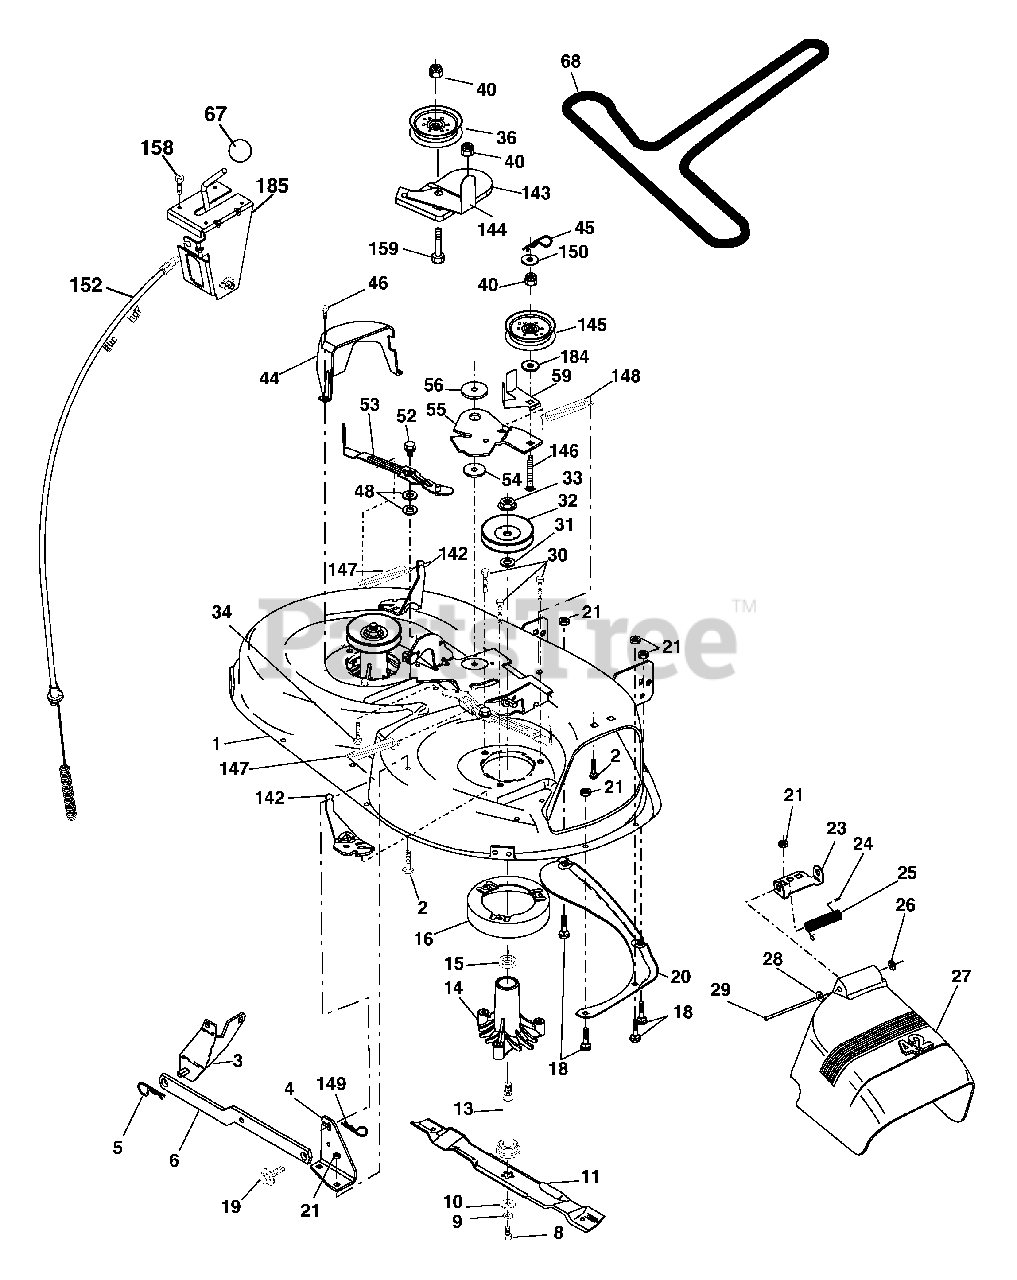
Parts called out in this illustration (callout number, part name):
1	Mower Deck Assembly, 42"
2	Bolt
3	Bracket Asm Fr. Sway Bar 3/42
4	Bracket Asm Deck 42" Sway Bar
5	Retainer Spring
6	Bar Sway Deck
8	Bolt 3/8-24 x 1.25 Gr. 8 patched
9	Washer, Lock
10	Washer, Hardened
11	Blade Mower 42" Hi-Lift
11	Blade, Mulching 42" Std
11	Blade Mulching 42" Premium
13	Shaft Assembly, Mandrel, Vented
14	Housing, Mandrel, Vented
15	Bearing, Ball, Mandrel
16	Stripper, Mandrel Deck
18	Bolt, Carriage 5/16-18 x 5/8
19	Bolt, Shoulder
20	Baffle, Vortex
21	Nut
23	Bracket, Deflector Mower 42"
24	Cap, Sleeve 80 x 112 Blk Mower
25	Spring, Torsion, Deflector 2 52
26	Nut, Push Phos & Oil
27	Shield, Deflector 42" Blk
28	Washer 11/32 x 5/8 x 16 Ga.
29	Rod, Hinge 42" 6 75 W/G
30	Screw Thdrol
31	Washer, Spacer Mower Vented
32	Pulley, Mandrel
33	Nut, Toplock
34	Bolt Carr SH 3/8-16 x 1-1/2 Gr.5
36	Pulley, Idler, Flat
40	Nut Lock 3/8-16
44	Guard, Mandrel, LH
45	Retainer
46	Screw, Thdrol 1/4-20 x 5/8 T
48	Washer, Hardened
52	Bolt, Shoulder 5/16-18 unc
53	Arm Assembly, Pad, Brake
54	Washer, Hardened
55	Arm, Idler
56	Spacer, Retainer
59	Guard TUV Idler
67	Knob Round
68	V-Belt, 42" Mower
142	Arm Spring Brake Mower
143	Bracket Arm Idler 42"
144	Keeper Belt 42" Clutch Cable
145	Pulley Idler Flat
146	Bolt Carriage Idler
147	Spring Extension
148	Spring Return Idler
149	Retainer Spring Yellow
150	Washer 9/32 x 3/4 x 10 Ga.
152	Clutch Cable 42"
158	Screw Hex Thd Cut 1/4-20 x 1/2
159	Bolt Rdhd Sqn 3/8-16 unc x 1-3/4
184	Washer 13/32 x 7/8 x 10 Ga.
185	Head Asm Cable Clutch
